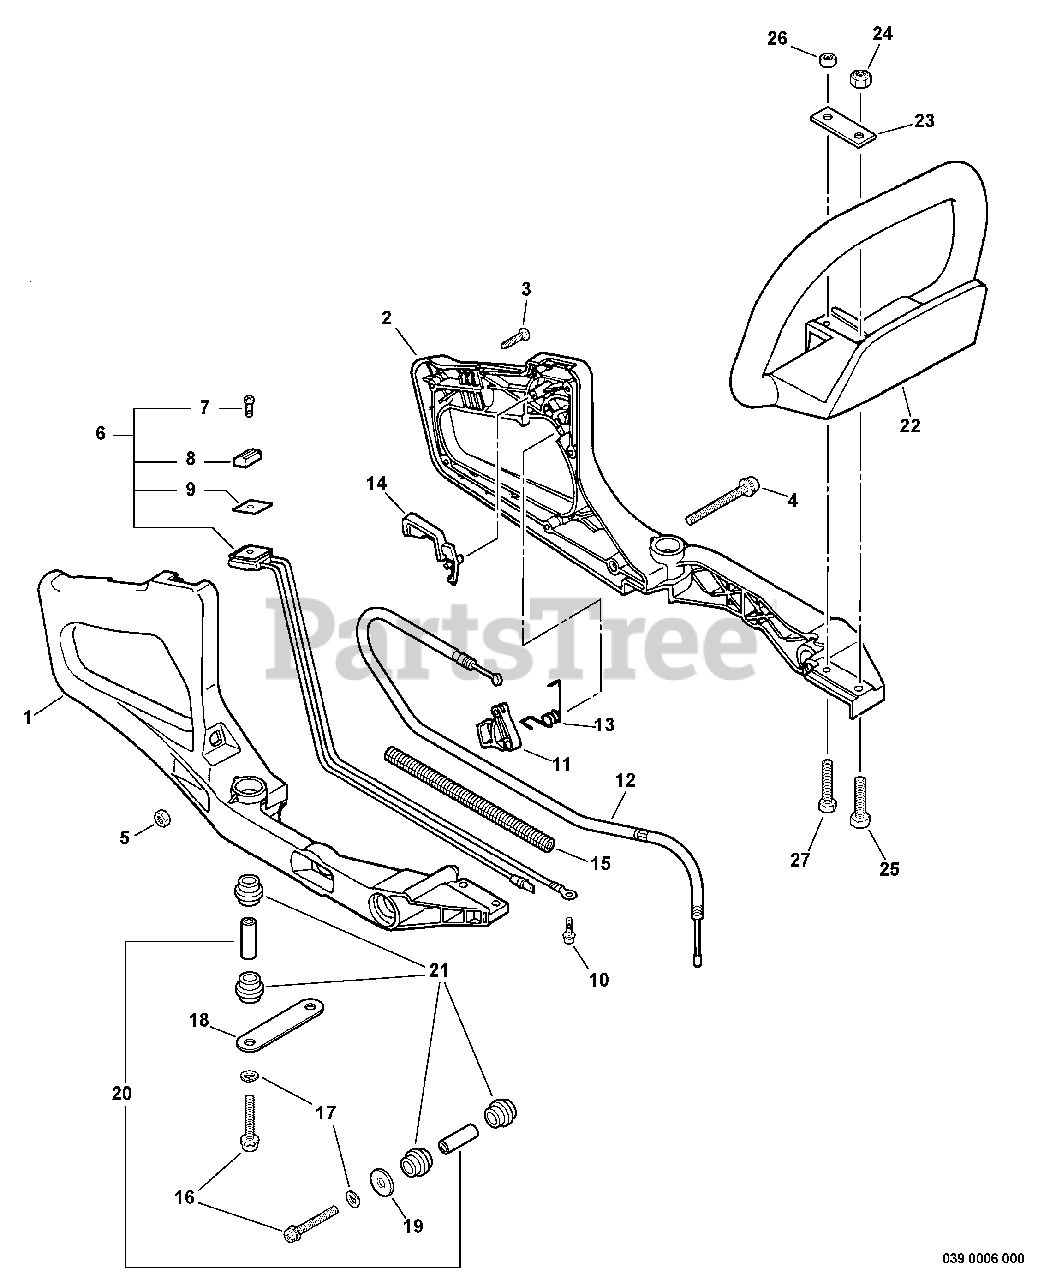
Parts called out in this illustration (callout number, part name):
1	HANDLE, REAR
2	HANDLE, REAR
3	SCREW 4×25
4	SCREW 5×64
5	NUT M5
6	IGNITION SWITCH ASSY
7	SCREW 3×10
8	KNOB, SWITCH - ORANGE
9	LABEL, SWITCH
10	SCREW 5×10
11	TRIGGER, THROTTLE
12	CABLE, THROTTLE
13	SPRING, TORSION
14	LOCKOUT, THROTTLE
16	SCREW 5×40
17	WASHER, SPRING 5
18	PLATE, EYE
20	SPACER
22	HANDLE, SUPPORT
23	PLATE, EYE
24	NUT, HEX M6
25	BOLT - 6×32
26	NUT M5
27	BOLT 5×35 SP
